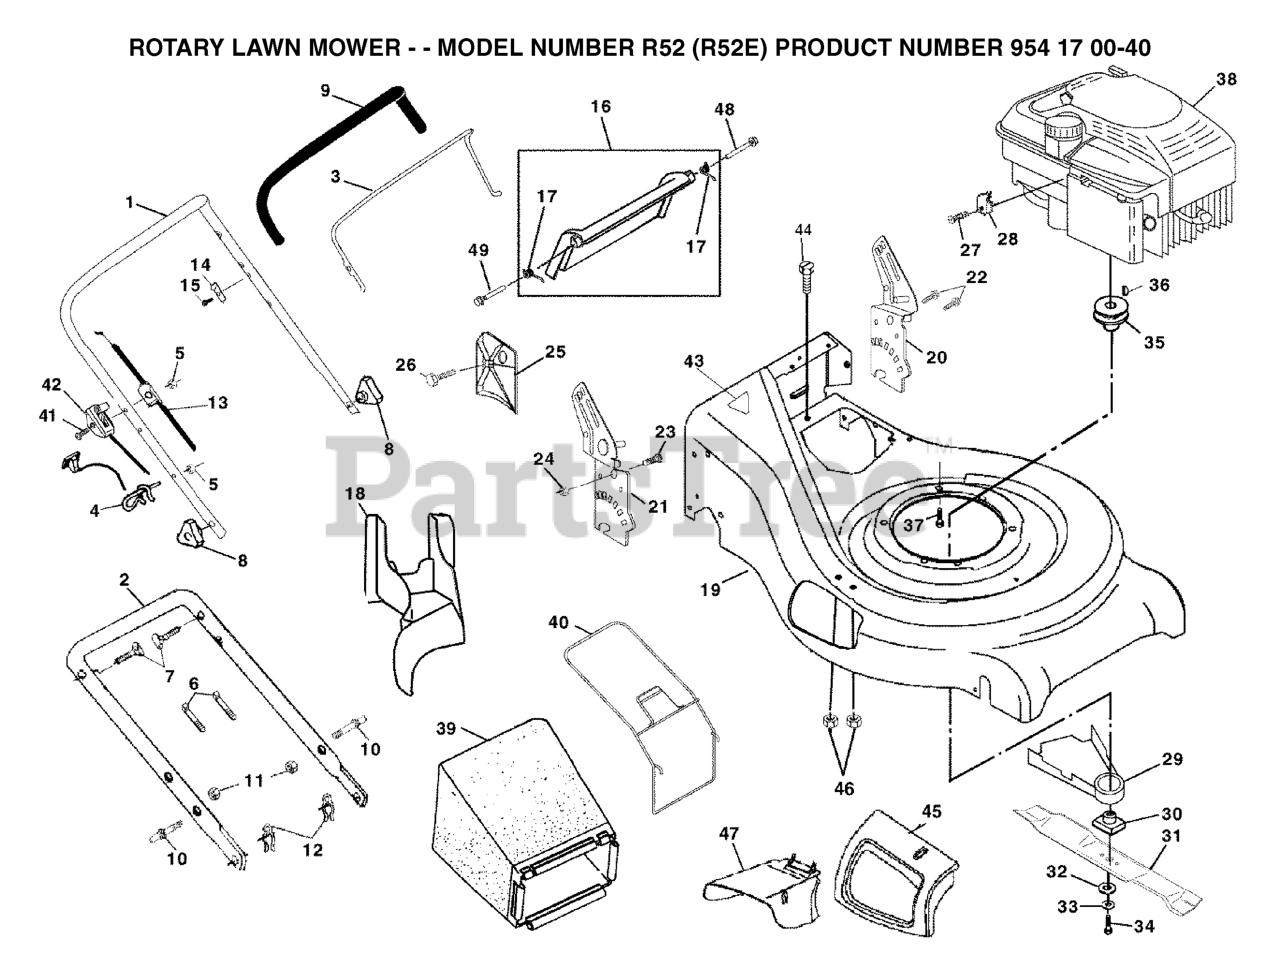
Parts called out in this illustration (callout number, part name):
1	HANDLE, UPPER DLX COMF. (GRIP)
2	HANDLE
3	CONTROL BAR
4	ROPE, GUIDE
5	NUT
6	TIE GUIDE
7	HANDLE BOLT
9	GRIP.HANDLE.FOAM
10	BOLT
11	NUT
12	HAIRPIN COTTER
13	ENGINE ZONE CONTROL
14	BRACKET UPSTOP
18	MULCHER PLUG
20	BRKT.HANDLE.ASM.RWGD.2
22	SELF-TAPPING SCREW 5/16-18X3/4
23	BOLT, HEX HEAD 5/16-18
24	NUT.71038.31-18.HEX.NYLOCK
25	CLIPPING DEFLECTOR
27	SCREW.HEX.HEAD.WASHER.10-16
28	CABLE CLAMP(ENGINE)
29	SHIELD.DEBRIS.21.RWGD.EZ
30	BLADE ADAPTOR
32	WASHER,HARDEN
33	LOCKWASHER
34	SCREW, HEX HD 3/8-24 X 1-3/8
35	ENGINE.PULLEY.FWG
36	HI PRO KEY PM WSL
37	BOLT 3/8-16X1-1/8
41	SCREW 1/4-20 X 2.12
42	CONTRL.THROTTLE.
43	DECAL.INTERNATIONL.CUTFINGER
45	DOOR.ASM.MULCH.21.RWD
47	DEFLECTOR.21.MCUT.RWGD.GRAY
48	SPRING.RH.REAR.DOOR.21.RWGD
49	SPRING.LH.REAR.DOOR.21.RWGD
